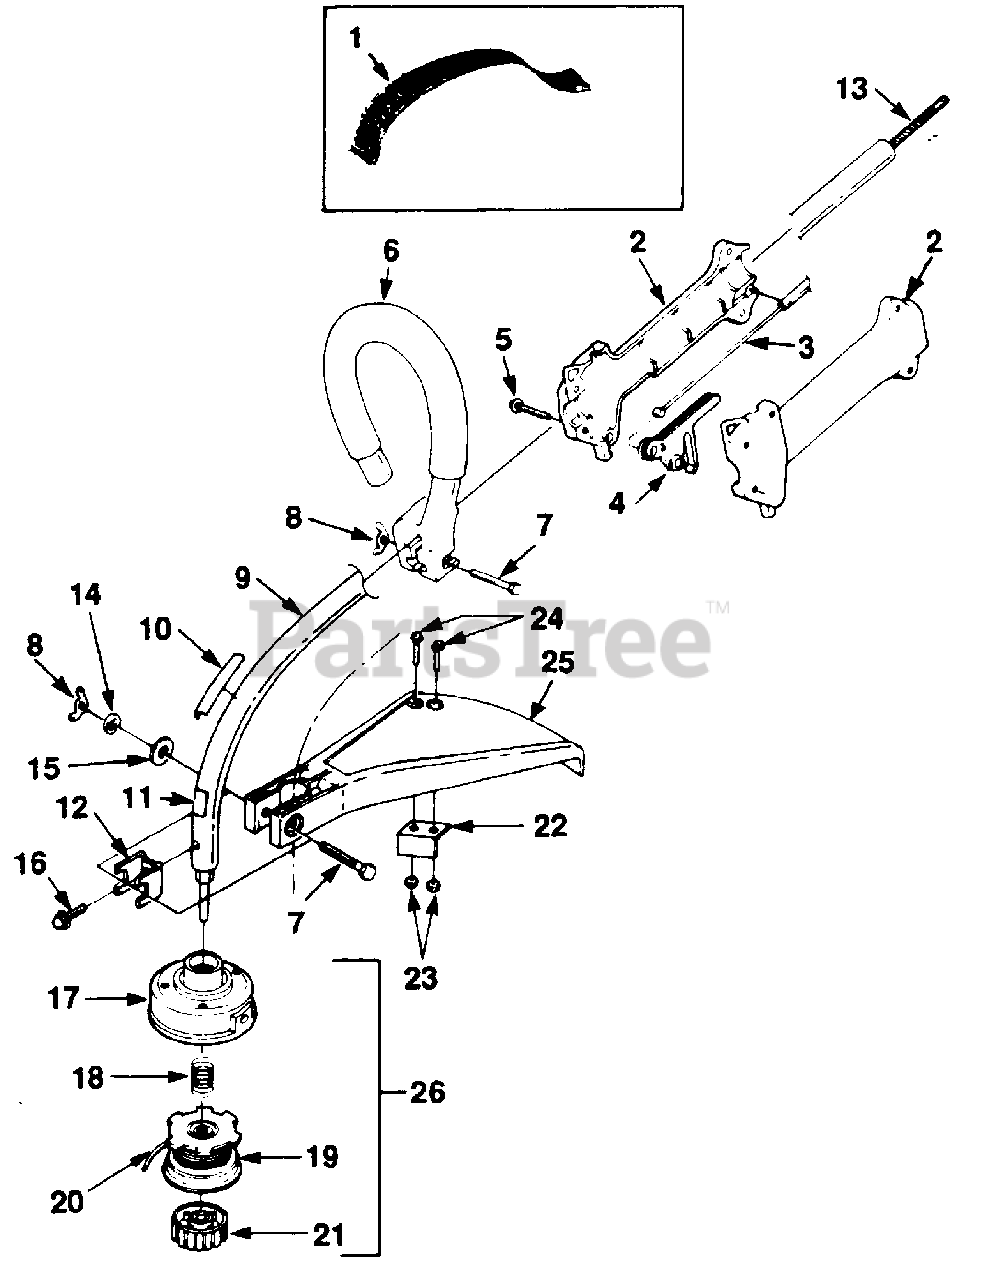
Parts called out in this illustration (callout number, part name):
1	HARNESS w/Connector (GST)
2	HANDLE GRIP ASSEMBLY
3	CABLE-Throttle
4	TRIGGER
5	SCREW-Plastite (#8 X 3/4")
6	HANDLE Front
7	SCREW-Hex Hd. (10-24 X 2")
8	NUT-Wing (10-24)
9	HOUSING Drive Shaft (Black)
10	DECAL-Starting Instructions
11	DECAL-Warning
12	CLAMP
13	SHAFT-Flex
14	WASHER Lock (1/4")
15	WASHER-Flat (1/4")
16	SCREW-(#10 X 1/2")
17	HOUSING & EYELET (Dual Line)
18	SPRING-Compression
19	SPOOL & STRING (ST-155, SX-135, ST-175G, HLT-15, GST-18, HGT)
20	LINE Replacement (.080" Dia. 1 lb. Box)(ST-155,SX-135,ST-175G,HLT-15,G
21	RETAINER Spool (R.H. Thread)
22	BLADE-Cut-Off (ST-155, SX-135, HLT-15)
22	BLADE Cut-Off (ST-175G, HGT, HLT-16)
23	NUT-Hex (10-24)
24	SCREW-Mach. Hex Hd. (10-24 X 7/8")
24	SCREW Mach Hex Hd. (10-24 X 7/8")
25	DEFLECTOR-Grass (ST-155, SX-135, HLT-15, HGT, HLT-16)
26	STRINGHEAD COMPLETE (.080 Line)(ST-155,SX-135,ST-175G,HLT-15,GST-18,H
